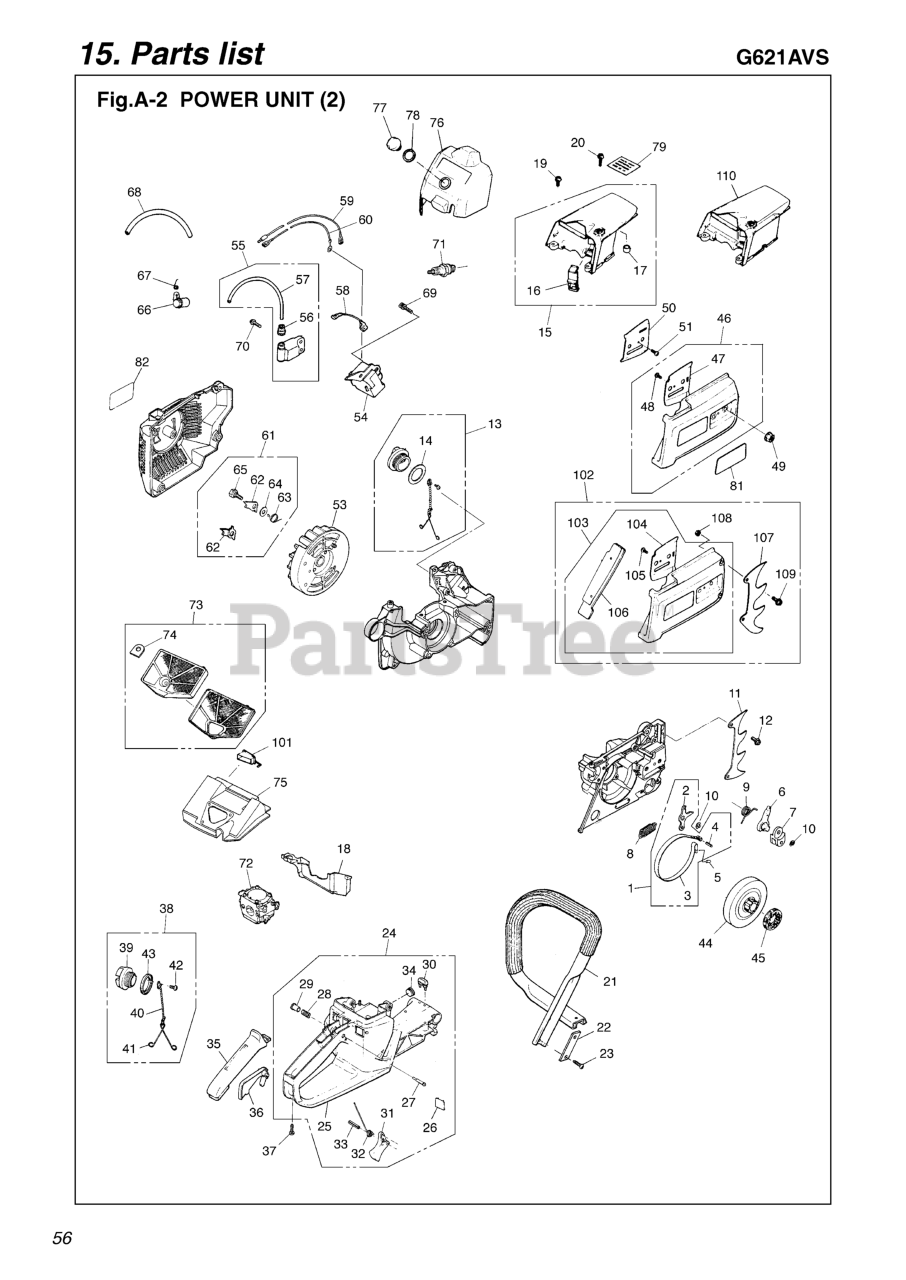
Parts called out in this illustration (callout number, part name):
1	BRAKE BAND COMP
2	BAND
3	ARM
5	ROLLER
6	LEVER
7	STOPPER
8	SPRING
9	SPRING
10	SNAP RING
11	SPIKE
12	SCREW
13	CAP ASSY
14	GASKET
15	COVER COMP.
16	CAP
19	SCREW
21	LEFT HANDLE COMP
22	PLATE
23	SCREW
24	RIGHT HANDLE ASSY
25	RIGHT HANDLE COMP
27	STOPPER
28	SPRING
29	KNOB
30	DAMPER (A)
31	LEVER
32	SPRING
33	PIN
34	DAMPER (B)
36	ARM
37	SCREW
38	CAP ASSY
43	GASKET
44	DRUM
45	SPROCKET
46	CHAIN COVER ASSY
47	PLATE
49	NUT
50	PLATE
51	SCREW
53	ROTOR
54	SOURCE COIL
55	IGNITION COIL COMP
56	CAP
58	CORD
59	CORD
61	ROTOR COMP.
62	RATCHET
63	SPRING
65	BOLT
67	SPRING
69	BOLT
71	SPARK PLUG
72	CARBURETOR
73	AIR CLEANER COMP
74	PLATE
75	SILENCER
76	COVER COMP
77	KNOB
78	GASKET
101	CAP
102	DOUBLE SPIKE KIT
103	CHAIN COVER ASSY
104	PLATE
105	SCREW
106	PROTECTOR
107	SPIKE
108	NUT
109	SCREW
110	COVER
